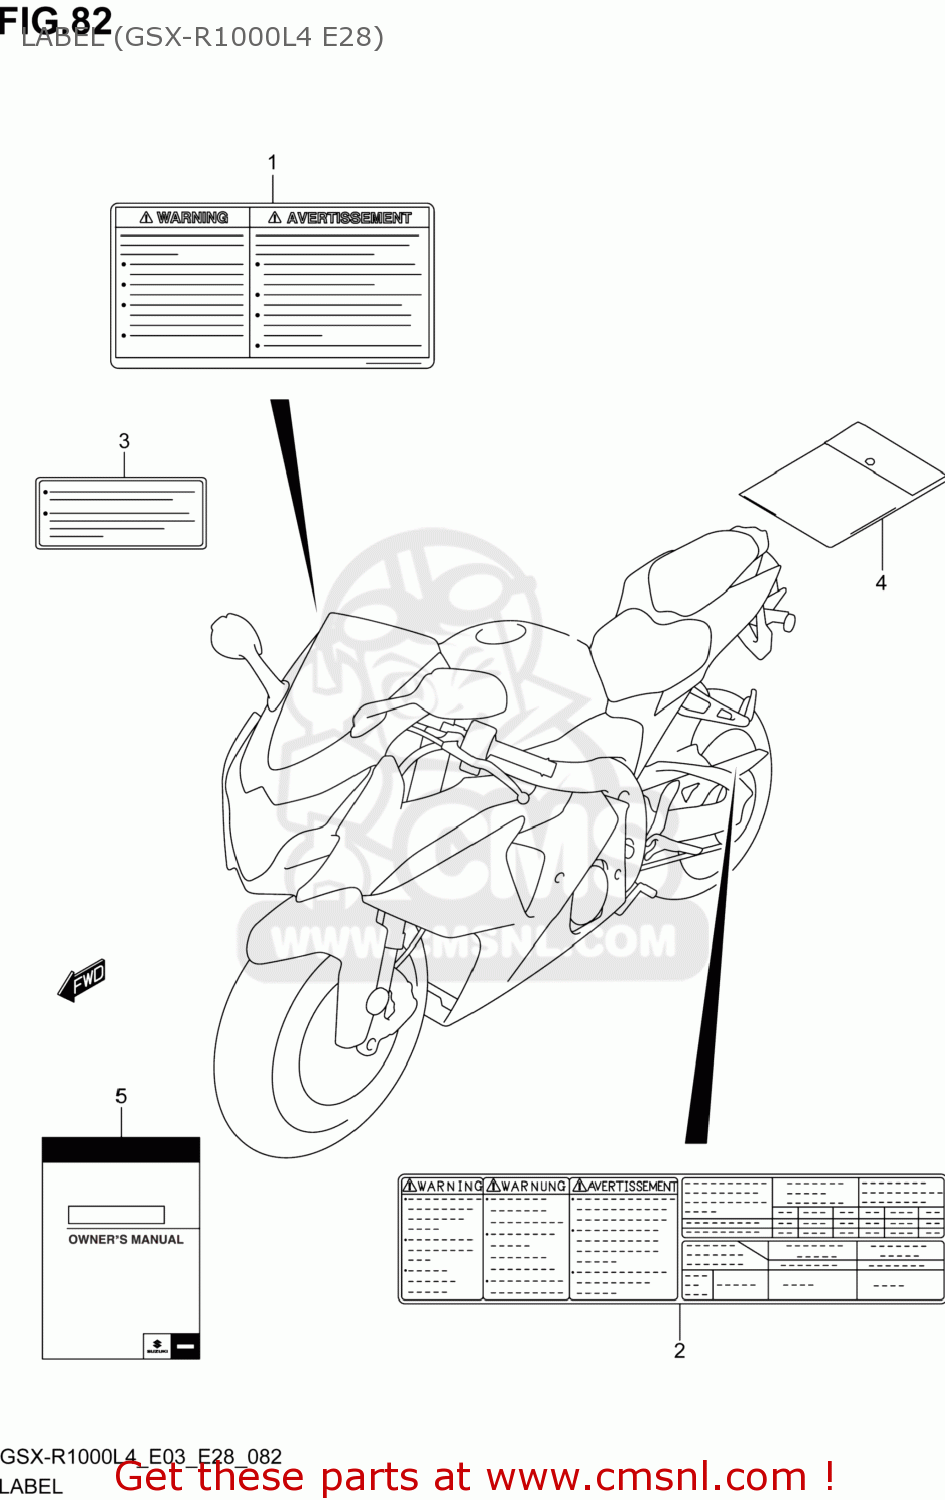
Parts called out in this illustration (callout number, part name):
1	LABEL,GENERAL WARNING
2	LABEL,TIRE INFORMATION
3	LABEL,FUEL INFORMATION
4	BAG,OWNER'S MANUAL
5	MANUAL,OWNER'S
